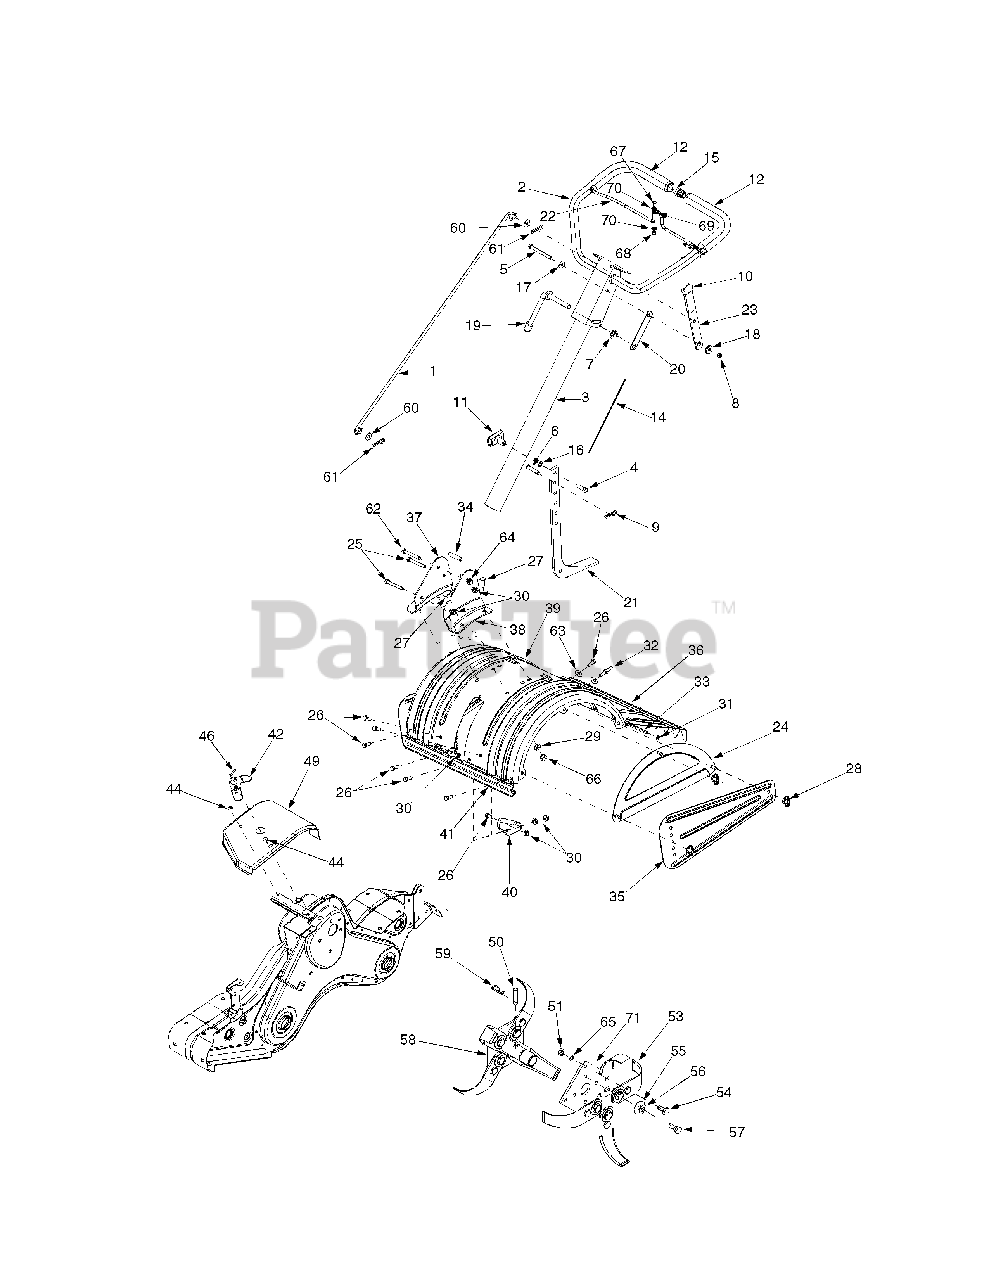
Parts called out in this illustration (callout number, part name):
1	Shift Rod
4	Hex Screw 3/8-16 x 1 25
5	Hex Screw 5/16-18 x 3 25
6	Clevis Pin 3/8-1 62
7	Flange Lock Nut 3/8-24
8	Hex Lock Nut 5/16-18
9	Cotter Pin
14	Cable Tie
15	Plug
16	Flat Washer 3/8 ID x 620 OD
17	Bell Washer 340 ID x 872 OD
18	Shoulder Spacer
19	Handle Adjustment Crank
20	Hex Nut Retainer Bracket
25	Hex Cap Screw 5/16-18 x 2 75
26	Hex Cap Screw 5/16-18 x 750
27	Carriage Bolt 3/8-16 x 1 0
29	Lock Washer 3/8
30	Flange Nut 5/16-18
32	Hex Screw 5/16-18 x 75"
34	Spacer 322 x 625 x 2 0
42	Shift Crank Ass’y
44	Screw 1/4-14 x 625
46	Spiral Pin 3/16 x 1 0
51	Hex Nut 3/8-24
54	Shoulder Bolt
55	Flat Washer 51" ID x 1 50" OD
56	Bell Washer 515" ID x 1 14" OD
57	Shoulder Bolt
59	Internal Cotter Pin
60	Rubber Washer
61	Cotter Pin
62	Hex Screw 3/8-16 x 2 75"
63	Flat Washer
64	Flange Nut 3/8-16
65	Lock Washer
66	Hex Nut 3/8-16
67	Truss Screw 1/4-20 x 65
68	Hex Lock Nut 1/4-20
69	Battery Hose Clamp 5/16
70	Flat Washer 260 ID x 720 OD
